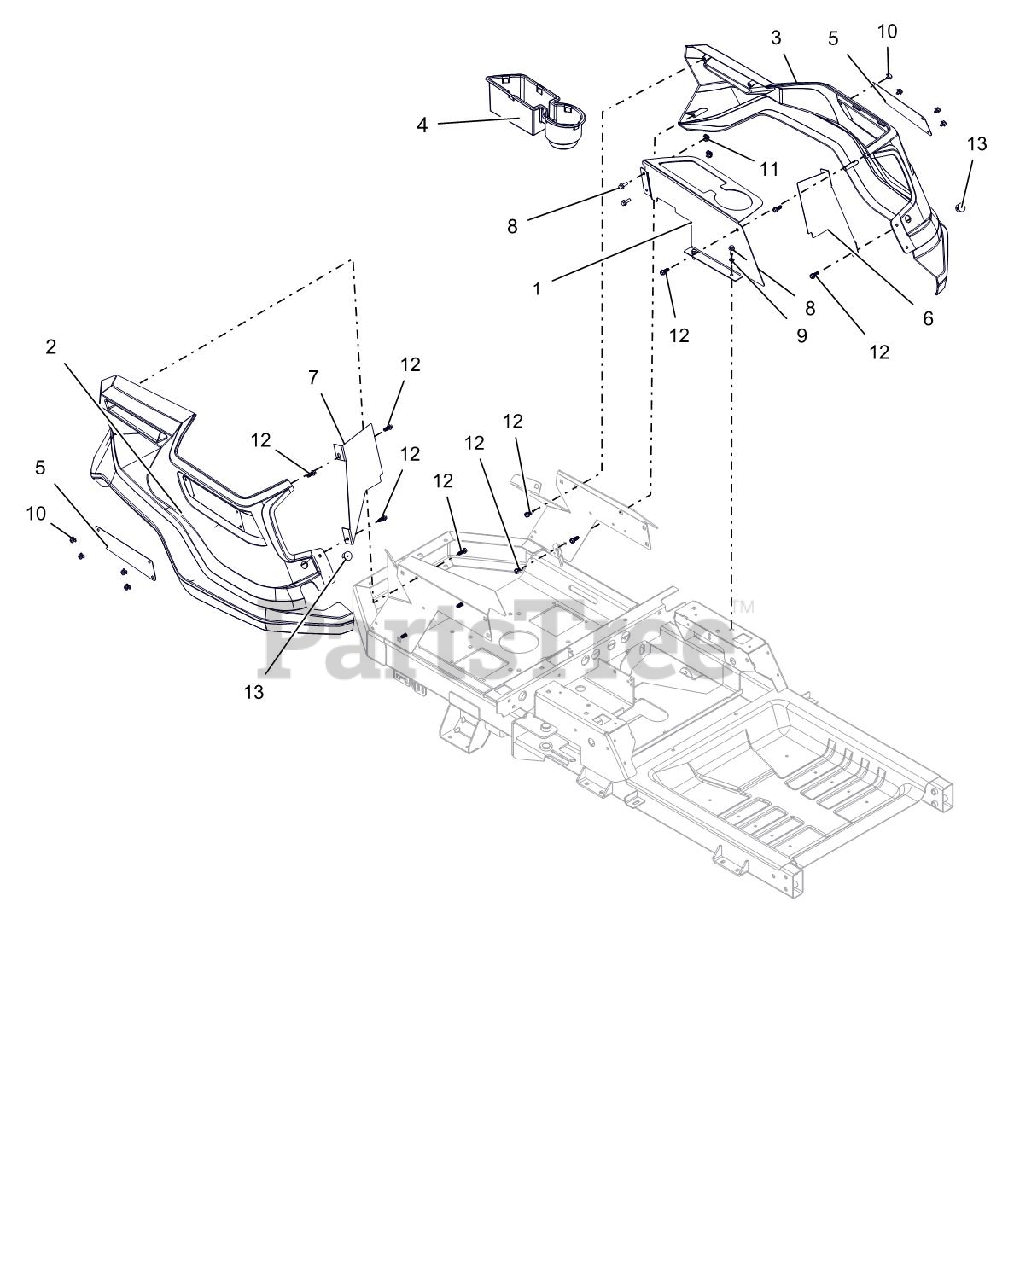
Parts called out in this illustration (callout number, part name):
1	PANEL, LEFT SIDE FENDER MOUNT
2	FENDER, RH IKON
3	FENDER, LH IKON
4	INSERT, CUP/STORAGE HOLDER
5	PLATE, ARIENS NAME
6	PLATE, LH BLOCKER
7	PLATE, RH BLOCKER
8	BLT,HEX-FLG .25-20X.75 G5 BFP
9	@WSHR-LK .25X.062 REG YWZC
10	RIVET, PLASTIC .195 DIA.
11	NUT RETNR .25-20
12	SCR-.312X.75 #14H H/W/H H/L CZ
13	PLUG, HOLE .75 (BLACK)
